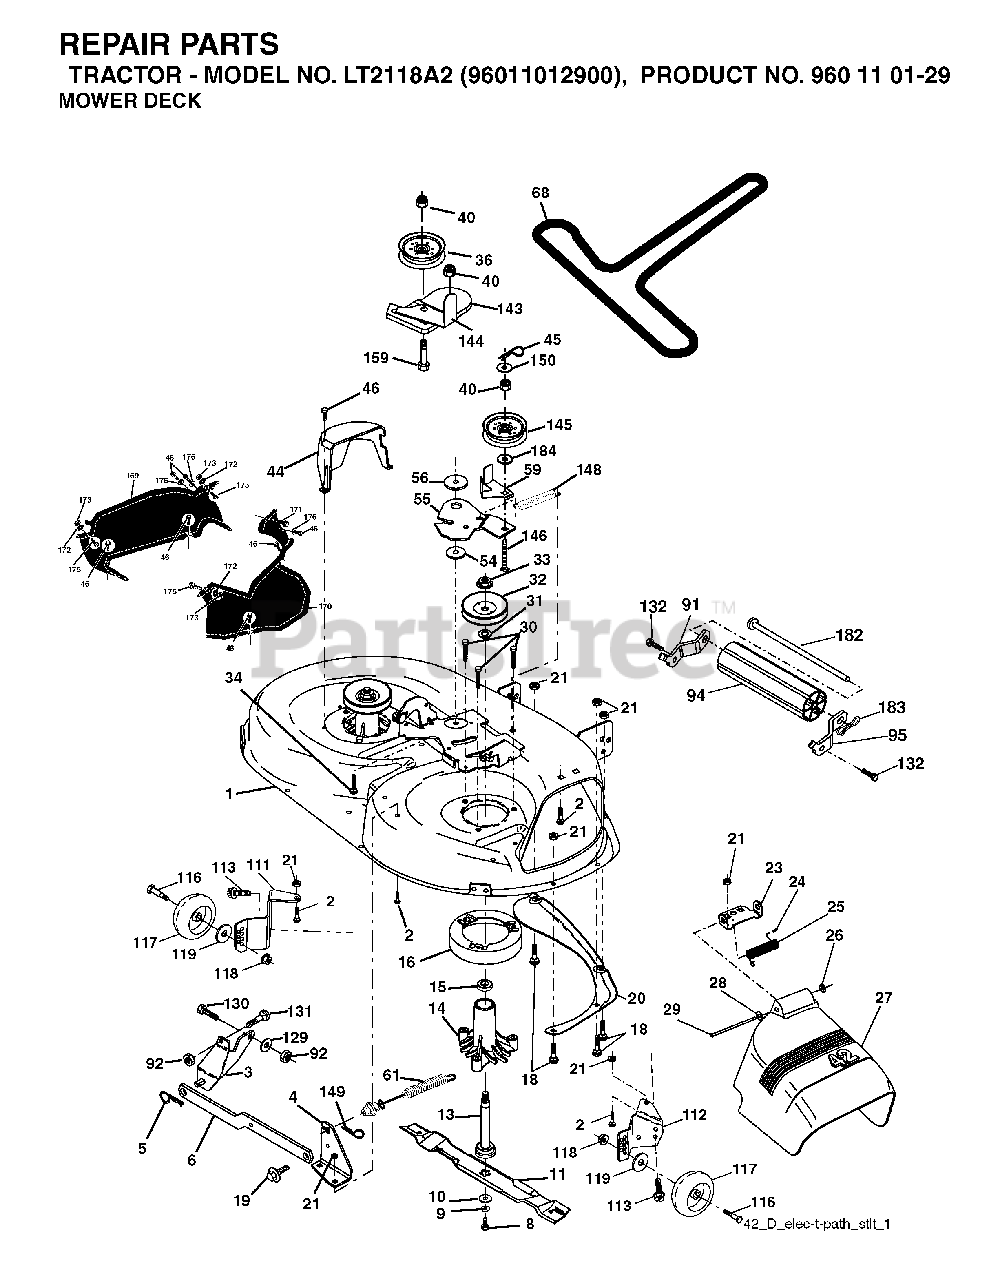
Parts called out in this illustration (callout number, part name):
1	42" DECK KIT
2	BOLT
3	BRKT ASM SWAY BAR
4	BRACKET SWAY BAR 42" DECK
5	RETAINER-SPRNG RB
6	BAR SWAY DECK
8	BLADE BOLT
9	LOCKWASHER
10	WASHER.BLADE
11	42" HI-LIFT BLADE
13	SHAFT ASM VENT
14	HSG MANDREL
16	STRIPPER, MWR ROUND
18	BOLT
19	BOLT SHD 5/16-18
20	BAFFLE.VORTEX
21	LOCKNUT
23	BRKT, DEFL. MOWER
24	CAP-SLEEVE LT
25	SPRING TORSION
26	NUT PUSH M
28	WASHER
29	ROD.HINGE
30	SCREW, WASHER HEAD
31	WASHER.SPACER.MANDREL
32	PULLEY/MANDREL
33	NUT.FLANGE.LOCK.TOP
34	BOLT.3/8-16X1.50
36	FLAT IDLER PULLEY
40	NUT LOCK FLG 3/8-16 UNC
44	GUARD MANDREL LH BLACK
45	RETAINER M
46	SCREW.1/4-20X5/8
55	ARM IDLER 42" MOWER LT/YT
56	SPACER.RETAINER.MOWER
59	GUARD, BELT
61	SPRING EXT ELEC CLUTCH
91	BRACKET ASM NOSEROLLER LH
92	NUT
94	NOSE ROLLER
95	BRACKET ASM NOSEROLLER RH
111	BRACKET, WHEEL
112	BRACKET, WHEEL
113	BOLT.5/16HEX.WHS.HD
117	WHEEL.GAGE.HALF.SPOKED
118	LOCKNUT
119	WASHER
129	WASHER
131	BOLT D
132	SCREW, 3/8-16X3/4
143	BRACKET, ARM IDLER
144	KEEPER.BELT.42".CLUTCH.CABLE
145	PULLEY
146	BOLT, CARRIAGE IDLER BLACK
148	IDLER RETURN SPRING
149	SPRING.RETAINER.YELLOW.ZINC
150	WASHER LT
159	BOLT
182	ROD ROLLER NOSE STANDARD
183	PIN.COTTER.7/16.BOW TI
184	WASHER
201	PUSH.NUT.ROUND.3/8.DIAM
